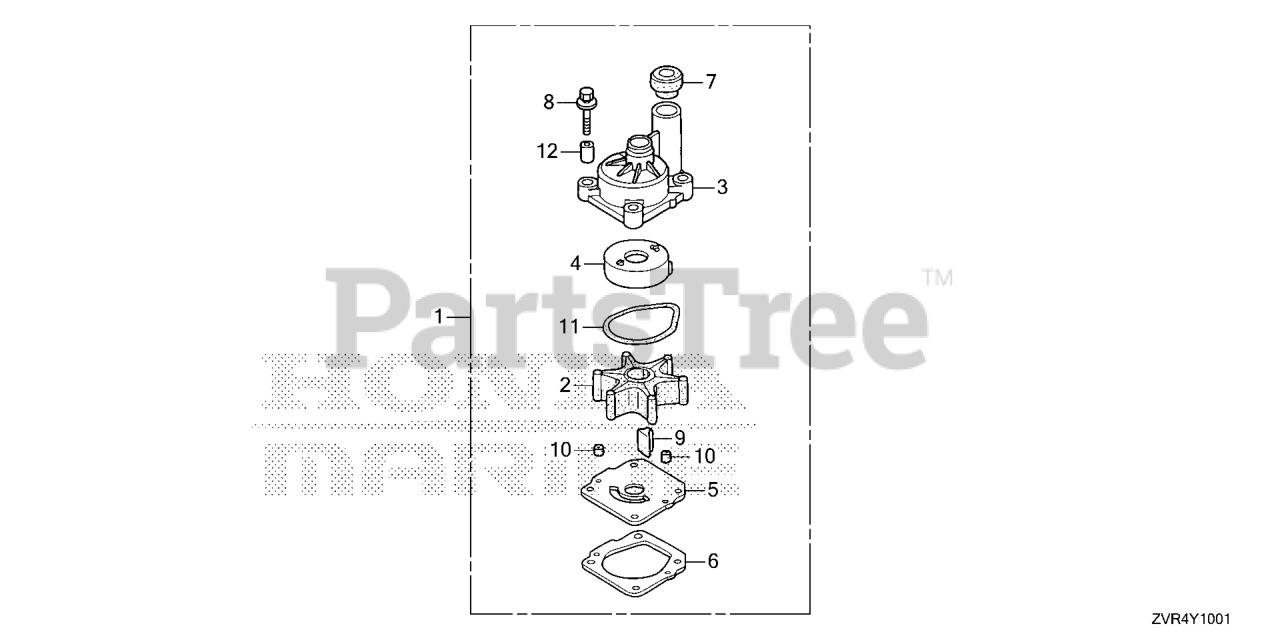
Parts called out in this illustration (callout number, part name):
1	PUMP KIT, IMPELLER
2	IMPELLER, PUMP
3	HOUSING, IMPELLER
4	LINER, PUMP
5	COVER, IMPELLER
6	GASKET B, IMPELLER
7	RING, WATER TUBE SEAL
8	BOLT-WASHER (8X40)
9	KEY, WOODRUFF
10	PIN, DOWEL (6X10)
11	O-RING, WATER PUMP
12	COLLAR, DISTANCE
